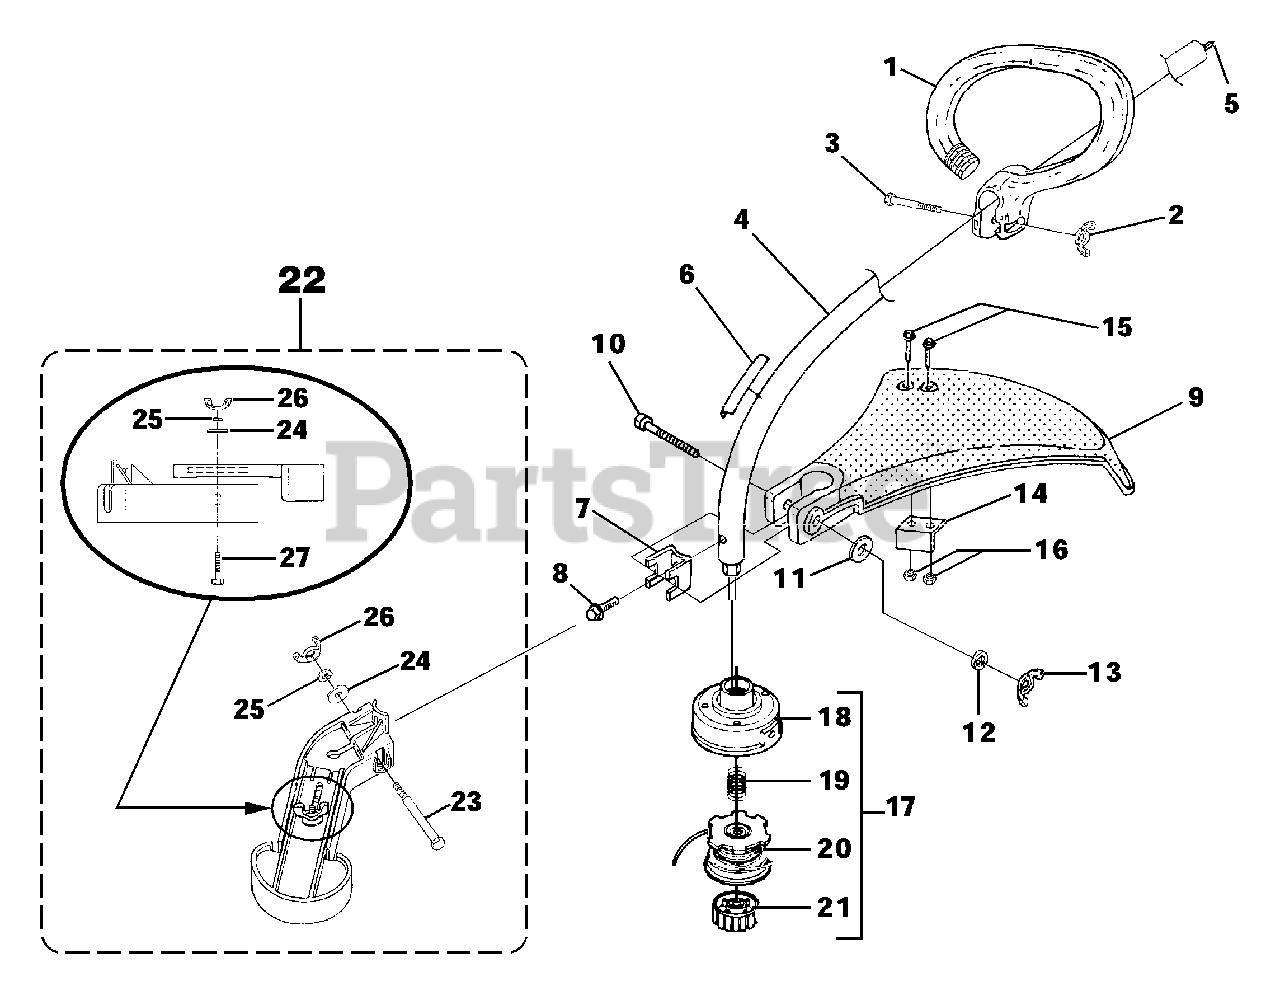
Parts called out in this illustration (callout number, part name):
1	HANDLE-Anti-Vibe
2	NUT-Wing, Washer Faced (1/4-20)
3	SCREW-Cap Hex Hd.
4	DRIVESHAFT HOUSING ASSY.
5	SHAFT-Flexible
6	DECAL-Warning
7	CLAMP
8	SCREW-Sems Hex Hd. (#10-24 X 3/8")
9	DEFLECTOR & BLADE KIT (55 Deg.)
10	SCREW-Cap Hex Hd. (10-24 X 2")
11	WASHER-Flat (1/4")
12	WASHER-Lock (1/4")
13	NUT-Wing, Washer Faced (1/4-20)
14	BLADE-Cut-Off
15	SCREW-Mech. Hex Hd. (10-24 X 7/8")
16	NUT-Hex (10-24)
17	STRINGHEAD-Complete (.080") (UT20694, UT20697, UT20702, UT20728)
18	HOUSING & EYELET (Dual Line)
19	SPRING-Compression
20	SPOOL & STRING (.080")
21	RETAINER-Spool (R.H. Thread, Black)
22	EDGER GUIDE KIT
23	SCREW-Hex Hd. (1/4-20 X 2 1/2")
24	WASHER-Flat (1/4")
25	WASHER-Lock (1/4")
26	NUT-Wing, Washer Faced (1/4-20)
27	SCREW-Hex Hd. (1/4-20 X 1")
